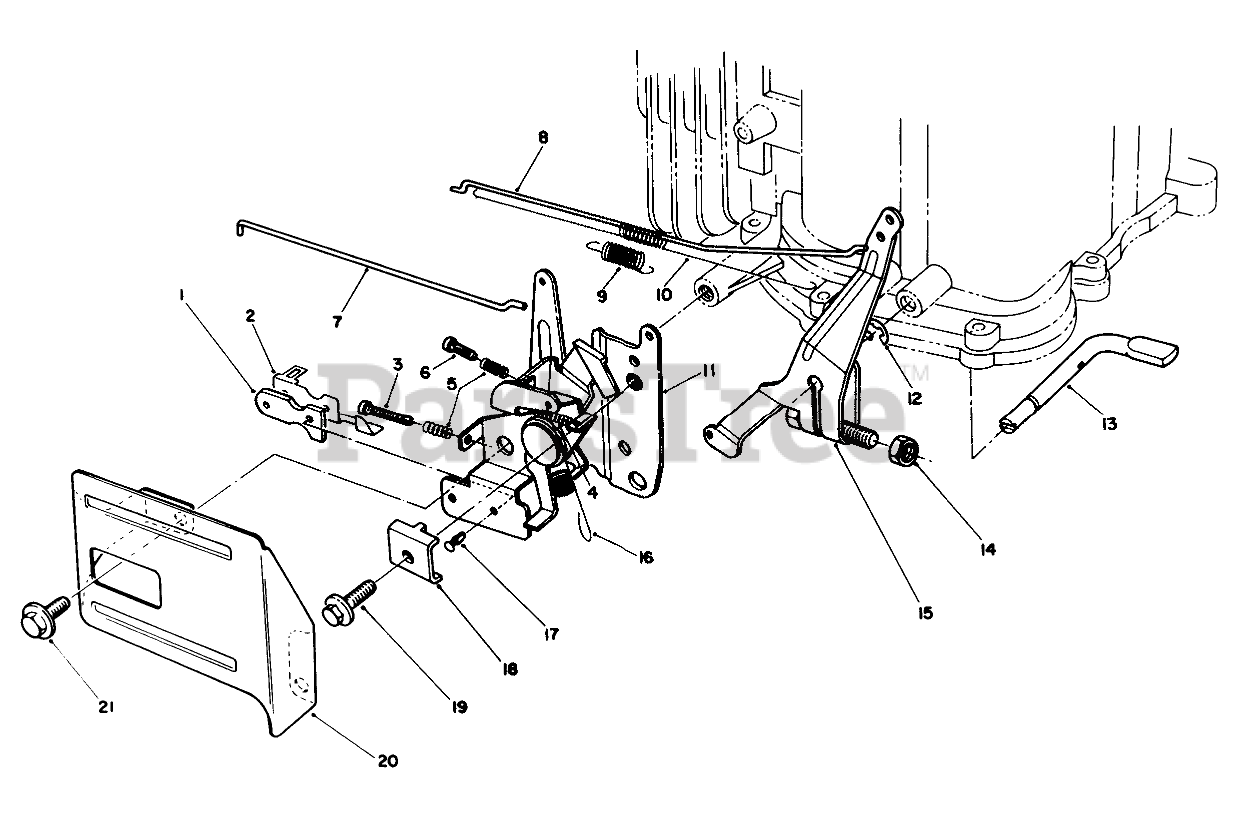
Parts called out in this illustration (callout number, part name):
1	INSULATOR-KILL SWITCH
2	TERMINAL-KILL SWITCH
3	SCREW
4	SPRING
5	SPRING
6	SCREW
7	Rod-Choke
8	Rod-Carburetor
9	SPRING
10	SPRING
11	THROTTLE
12	E-RING
13	SHAFT
14	Nut
15	ARM ASM
16	SPRING
17	RIVET
18	CLAMP-CABLE
20	THROTTLE GUARD
